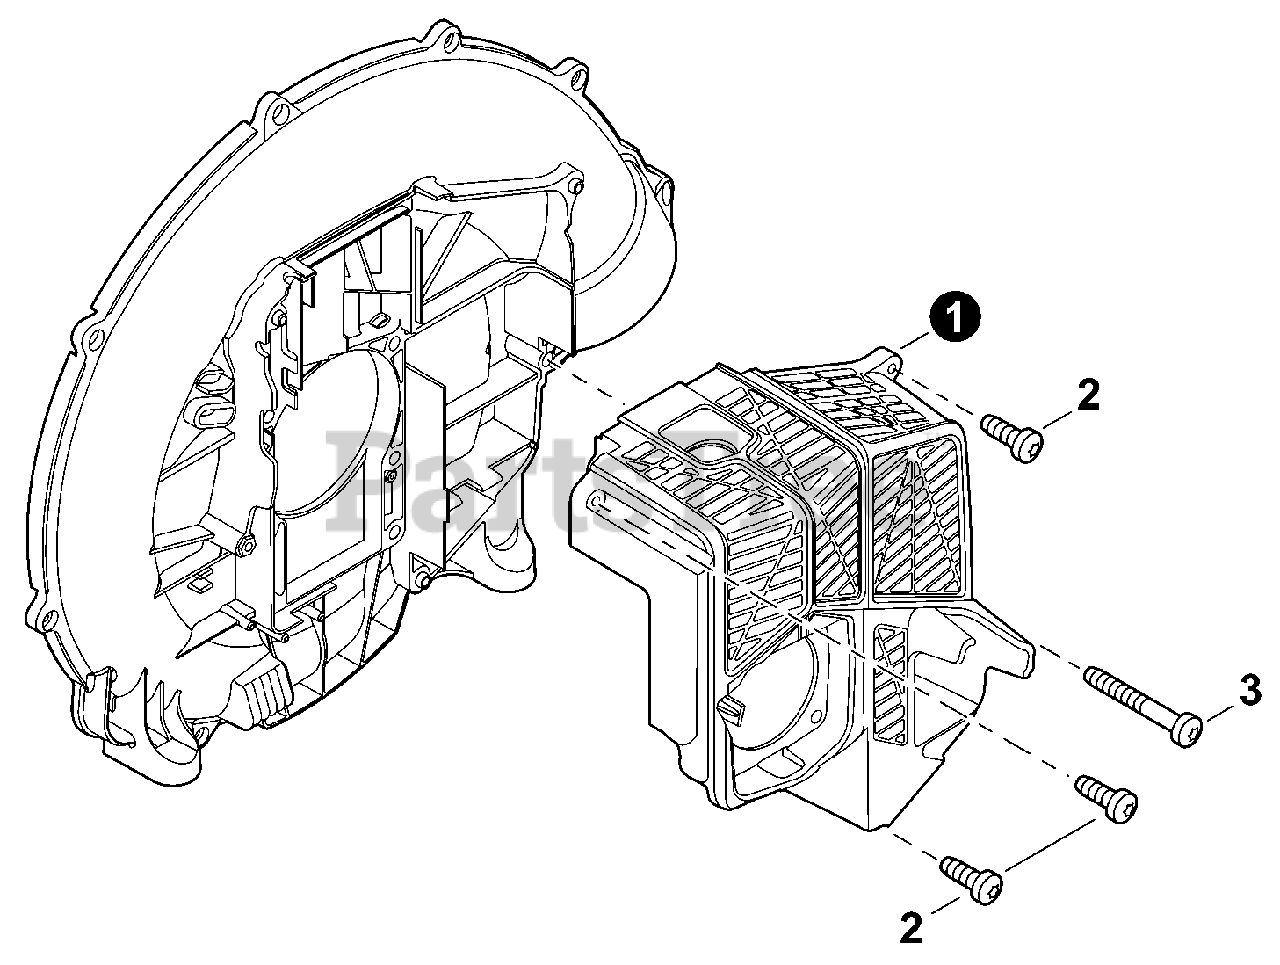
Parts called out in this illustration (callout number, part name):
1	COVER, ENGINE
2	BOLT, TORX 5×20
3	BOLT, TORX 5×55
